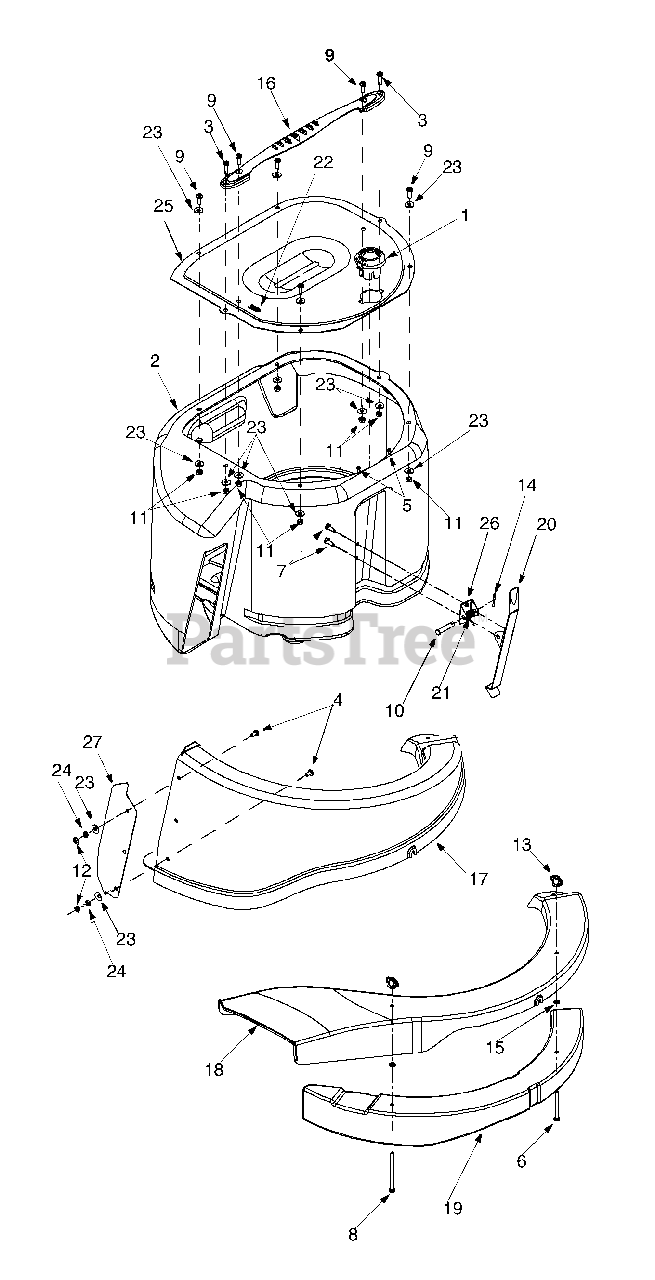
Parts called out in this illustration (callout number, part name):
1	Flow Indicator Assembly
2	Grass Bag Assembly
3	Machine Screw 1/4-20 x 1.0
4	Machine Screw 1/4-20 x 0.5"
5	Hex Screw #10-16 x 0.5"
6	Hex Screw 1/4-20 x 2.75"
7	Self-Tapping Screw 1/4-20 x 0.75"
8	Hex Screw 1/4-20 x 3.75"
9	Machine Screw 1/4-20 x 0.75"
10	Clevis Pin
11	Hex Sems Nut 1/4-20
12	Jam Nut
13	Wing Nut
14	Cotter Pin
15	Speed Nut
16	Bag Handle
17	Discharge Chute: Grass Bag
18	Side-Discharge Chute
19	Mulching Plug
20	Bag Release Lever
21	Torsion Spring
22	Clip Spring
23	Flat Washer
24	Lock Washer
